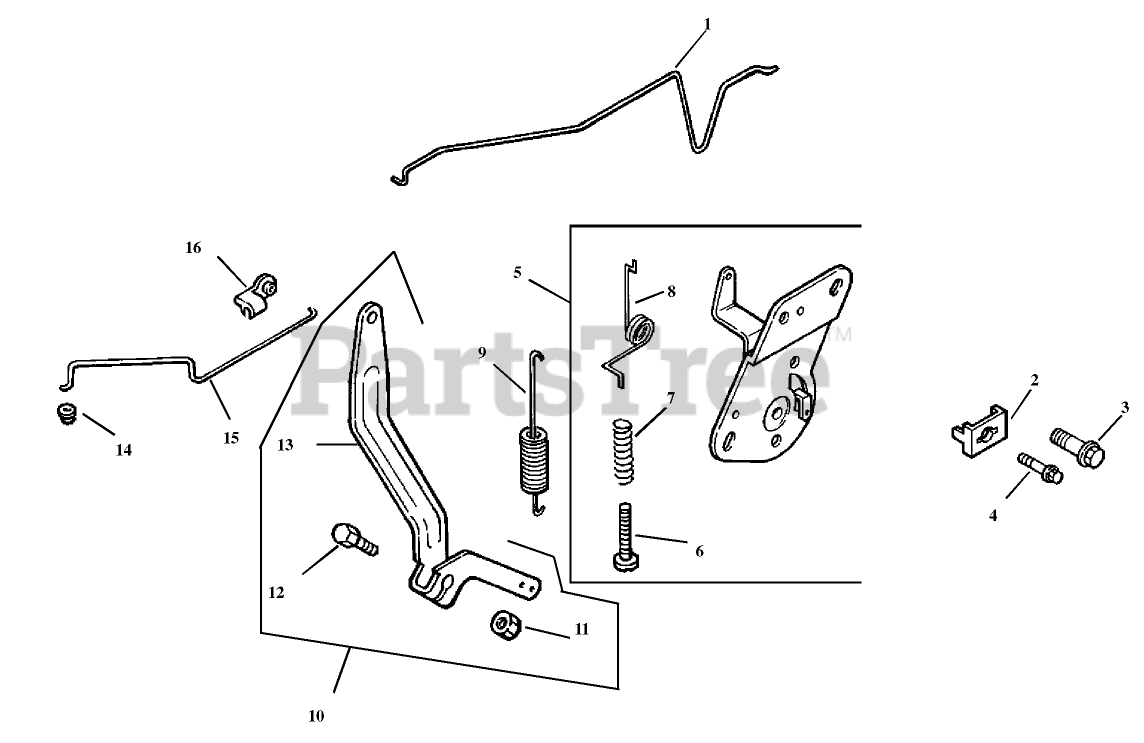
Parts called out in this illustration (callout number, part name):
1	Linkage-Choke
2	CLAMP-CABLE
3	Screw-Socket, 6 Lobed (Thread Forming, M6x1.0x20)
4	SCREW-FLANGE, THREAD FORMING (M5X0.8X16)
5	Control-Speed ASM(Incl. 6-8)
6	Screw-SPH,M4x0.7x25
7	Spring-Control, Speed
8	Spring-Return, Choke
9	Spring-Governor
10	Kit-Governor Lever (Incl. 11-13)
11	Nut-Flange, Hex (1/4-20)
12	Bolt-Square Neck, Round Head (1/4-20x1)
13	Lever-Governor
14	BUSHING-LINKAGE, THROTTLE
15	Linkage-Throttle
16	BUSHING-RETAINING, LINKAGE
